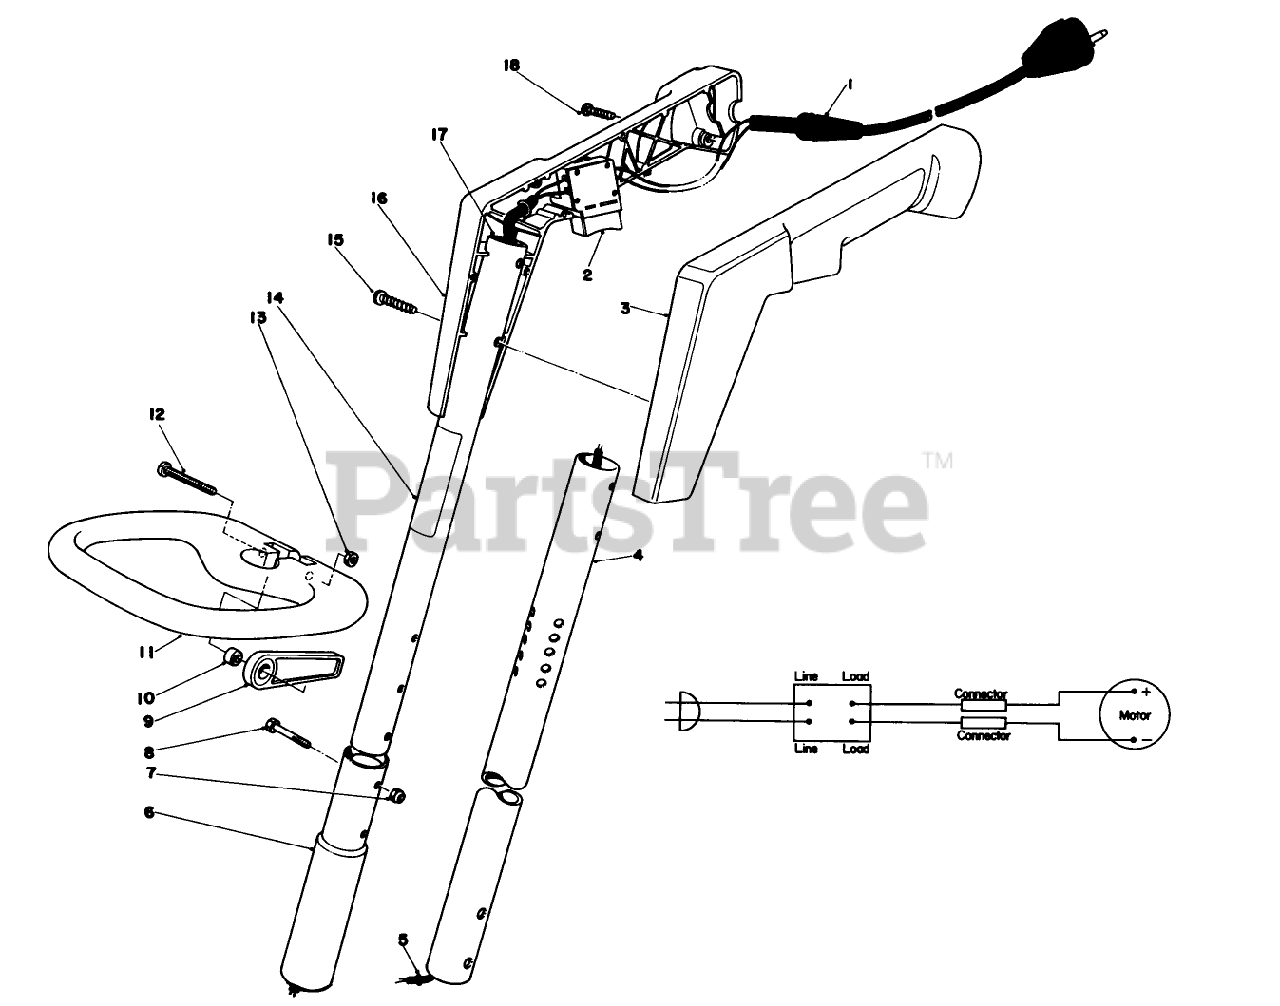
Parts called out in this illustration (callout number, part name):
1	Wiring Harness-Upper
2	SWITCH SINGLE SPEED
3	Left Hand Grip
4	Lower Tubing
5	WIRING HARNESS STD
6	Rain Shield
7	NUT-LOCK, NI
8	Machine Screw
9	Cam Lock
10	Spacer
11	HANDLE ADJUSTABLE
12	Screw
13	NUT-HEX
14	Decal-Caution
15	Pan Head Thread Forming Screw
16	Right Hand Grip
17	Upper Tubing
18	Pan Head Thread Forming Screw
